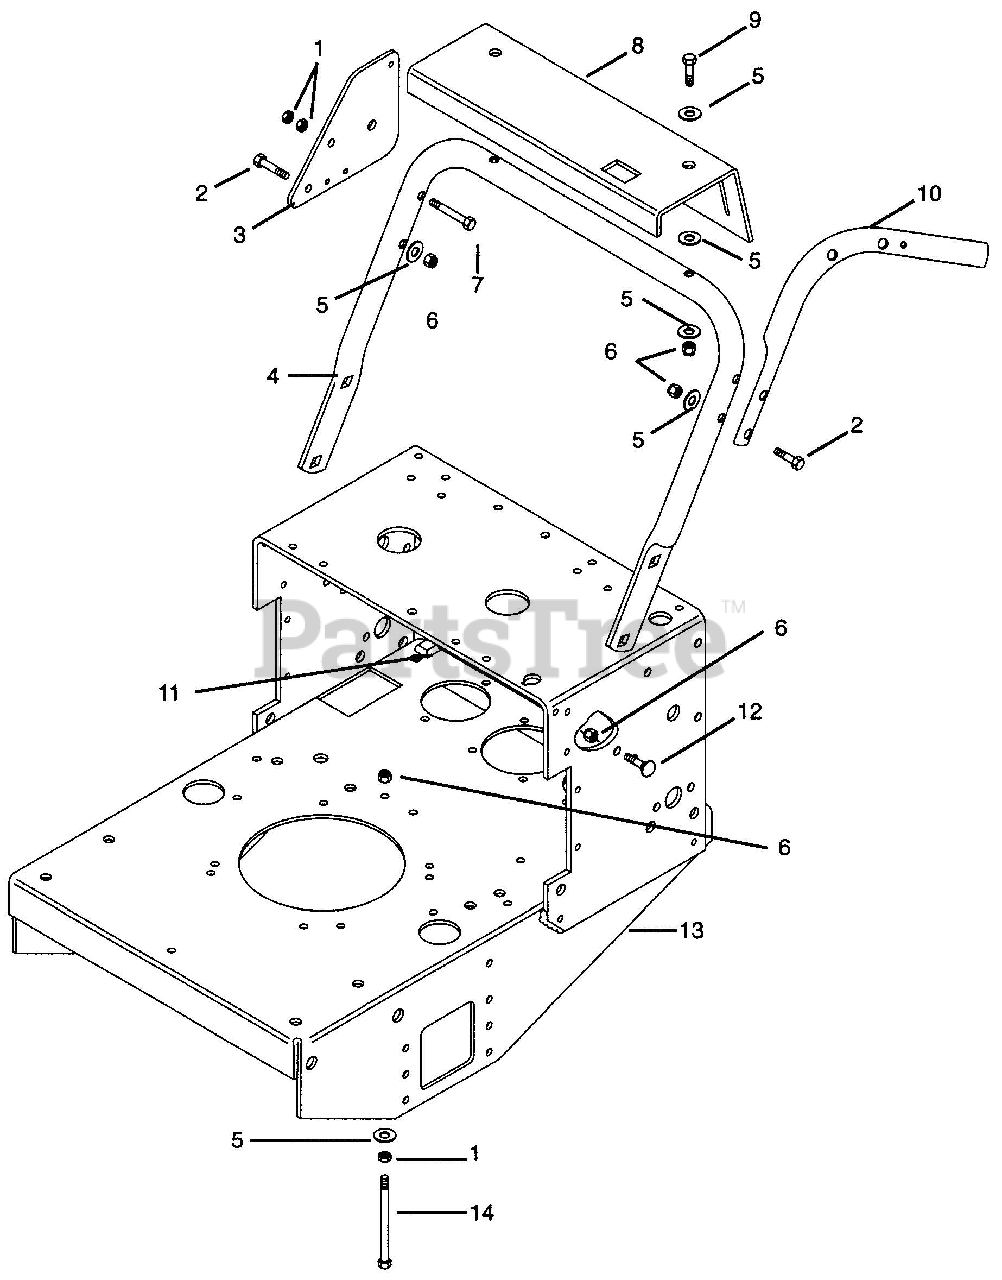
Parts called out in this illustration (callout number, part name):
1	Nut-Hex .375-16
2	Bolt-Hex, .38-16 x 2.25 Grade 5
3	Plate - Speed Control Lever
4	Tube - Handlrbar Mounting
5	Washer-Flat-Steel .406 x .812 x .065
6	Nut-Locking-Center .38-16
7	Bolt-Hex .38-16 x 2.50 Grade 5
8	Panel - Instrument
9	Bolt-Hex .38-16 x 2.00 Grade 5
10	Handlebar - Left Hand
10	Handlebar - Right Hand
11	Stop
12	Bolt-Round Head Square Neck .38-16 x 1.0
13	Weldment - Frame
14	Bolt-Hex .38-16 x 4.00
